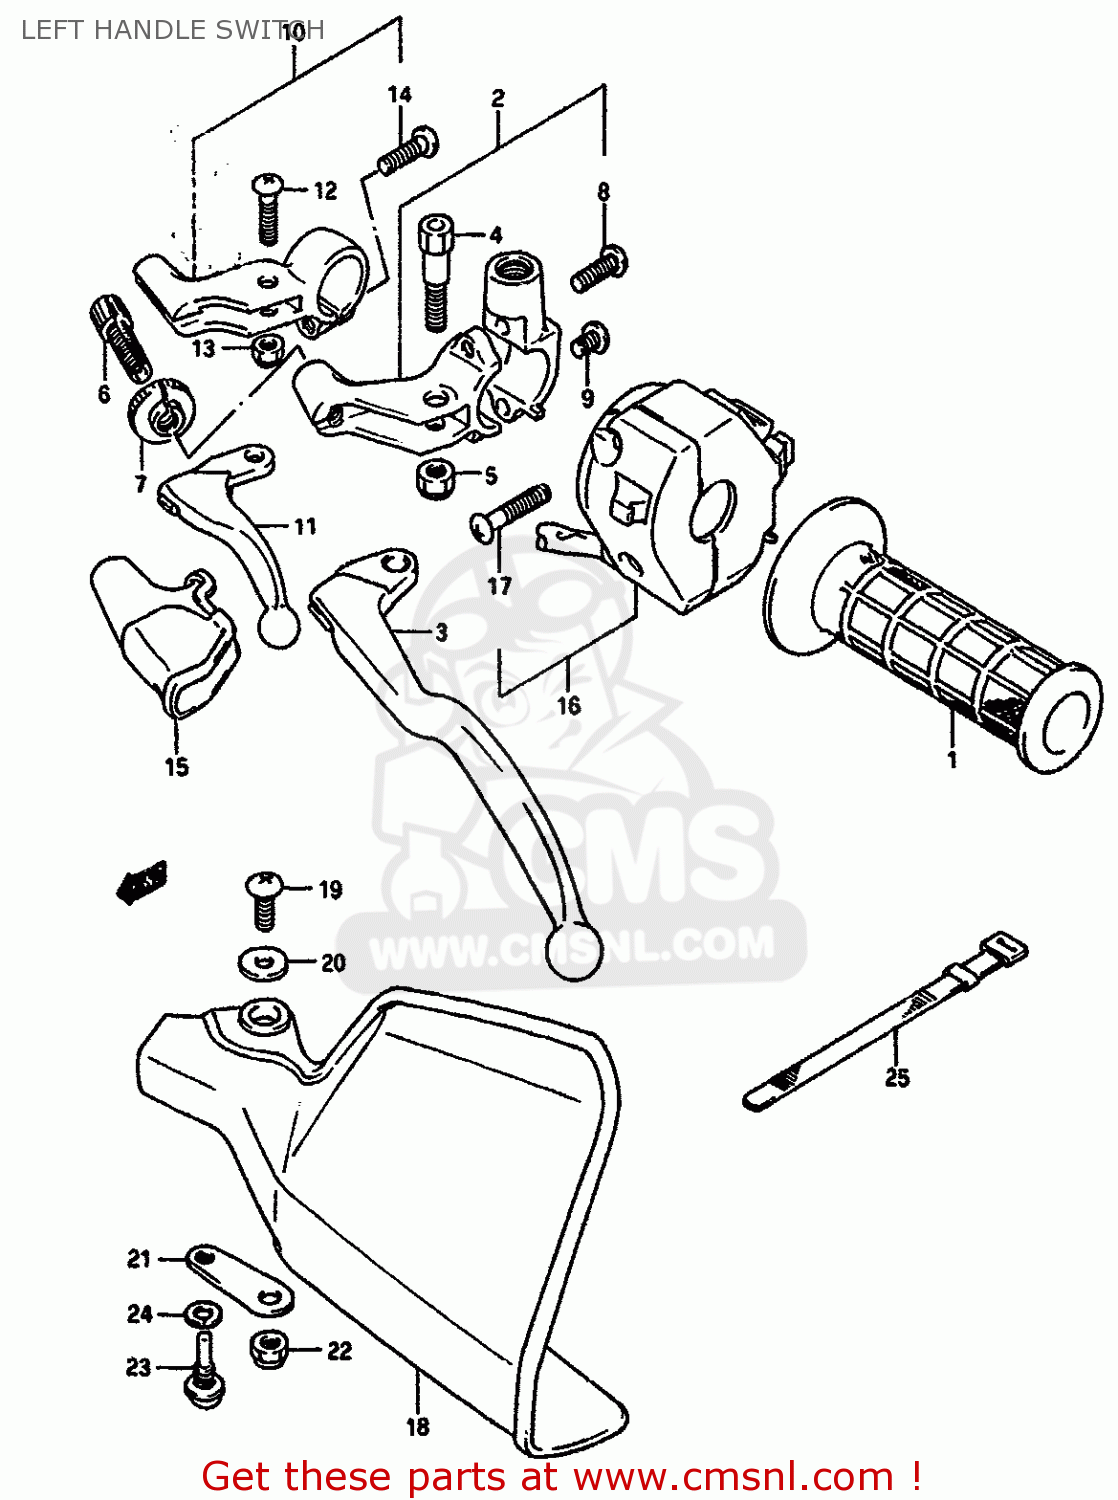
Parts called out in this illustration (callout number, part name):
1	GRIP,L
2	LEVER ASSEMBLY,CLUTCH
3	LEVER,CLUTCH
4	BOLT,LEVER SET
5	NUT 6MM
6	ADJUSTER,CABLE
7	NUT,LOCK
8	SCREW
9	SCREW(5X25)
10	LEVER ASSEMBLY,DECOMPRESSION
11	LEVER,DECOMP
12	BOLT,LEVER PIVOT
13	NUT
14	SCREW
15	COVER,DECOMP LEVER DUST
16	SWITCH ASSY,HANDLE LH
17	SCREW
18	COVER,KNUCKLE,LEFT
19	SCREW(5X10)
20	WASHER (5.5X16X1.2)
21	PLATE,KNUCKLE COVER,L LWR
22	NUT 6MM
23	SCREW
24	WASHER,LOCK
25	CLAMP(L:120)
